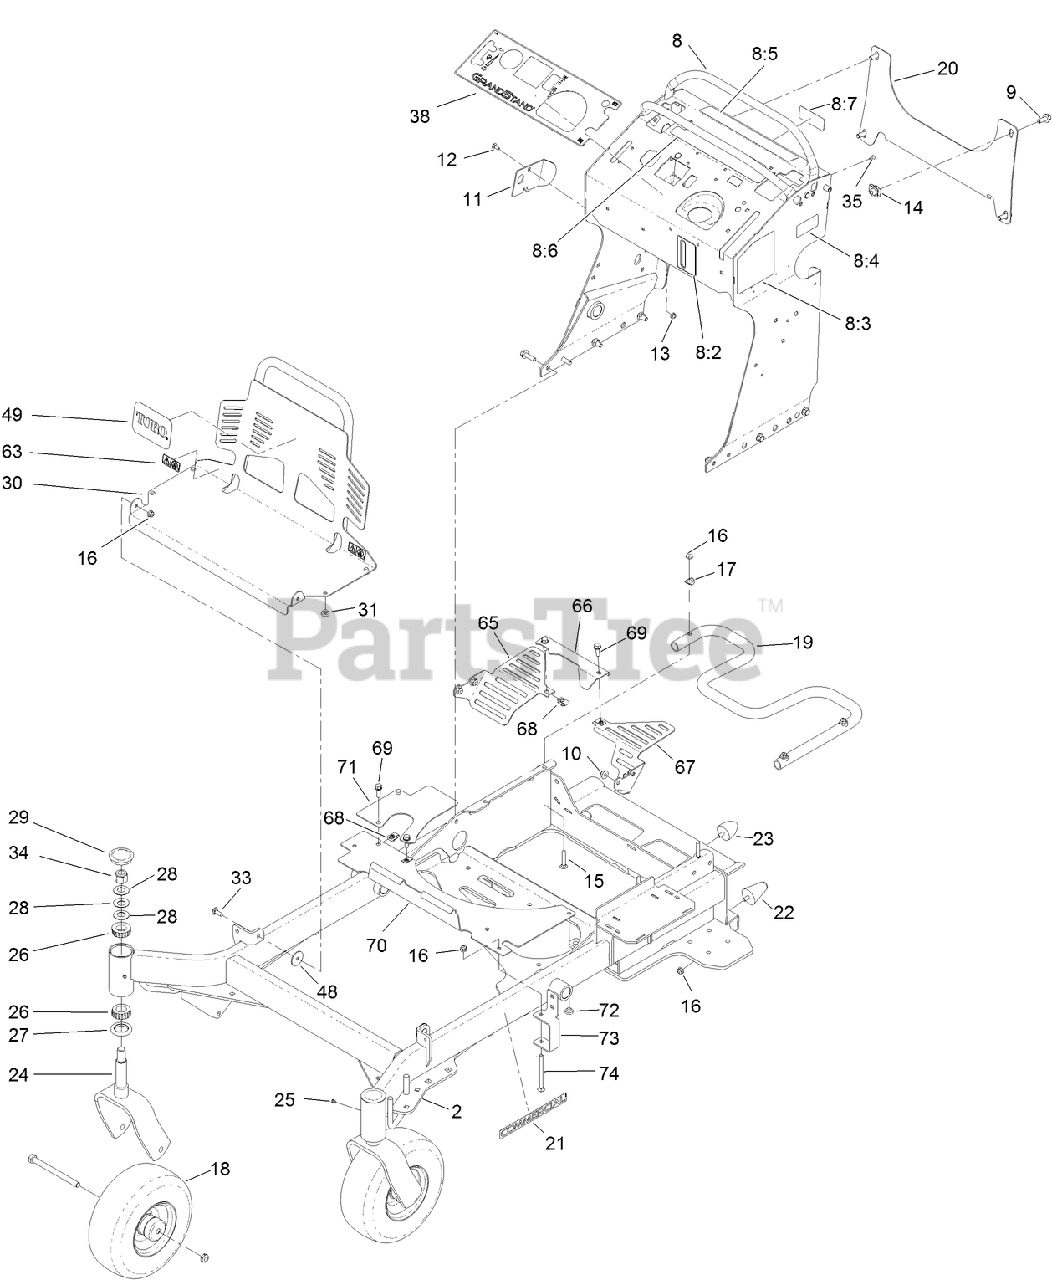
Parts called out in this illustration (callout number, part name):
8	TOWER DECAL ASM
8:2	DECAL-LEVEL, OIL
8:3	DECAL-SERVICE AID
8:4	DECAL-FILL, FUEL
8:5	DECAL-CAUTION
8:6	DECAL-CONTROLS
8:7	DECAL-FUSE
9	SCREW-HHF
10	NUT-HF, NI
11	PLATE-STRIKER
12	SCREW-CARR
13	NUT-HF
14	Nut-Tinnerman
15	SCREW-CARR
16	NUT-HF, NI
17	WASHER
18	WHEEL/TIRE AND BEARING ASM
19	TUBE-MOUNT, FUEL TANK
20	BRACKET-CROSS
21	DECAL-COMMERCIAL
22	BUMPER-RUBBER
23	BUMPER-RUBBER
24	FORK-CASTER
26	BEARING-ROLLER, TAPERED
27	SEAL-GREASE
28	WASHER-BELLVILLE
29	CAP-GREASE
30	GUARD-ENGINE
31	BUMPER
33	BOLT-CARR
34	NUT-LOCK, NI
35	RIVET-POP
38	DECAL-PANEL, CONTROL
48	WASHER-NYLON
63	DECAL-WARNING, NO RIDERS
65	GUARD-FAN, RH (CE)
66	GUARD-FAN, CENTER (CE)
67	GUARD-FAN, LH (CE)
68	NUT-U
69	SCREW-HHF
70	GUARD-EXTENSION
71	GUARD-BELT, CE
72	BUMPER
73	BRACKET-MOUNTING, GUARD
74	SCREW-CARR
